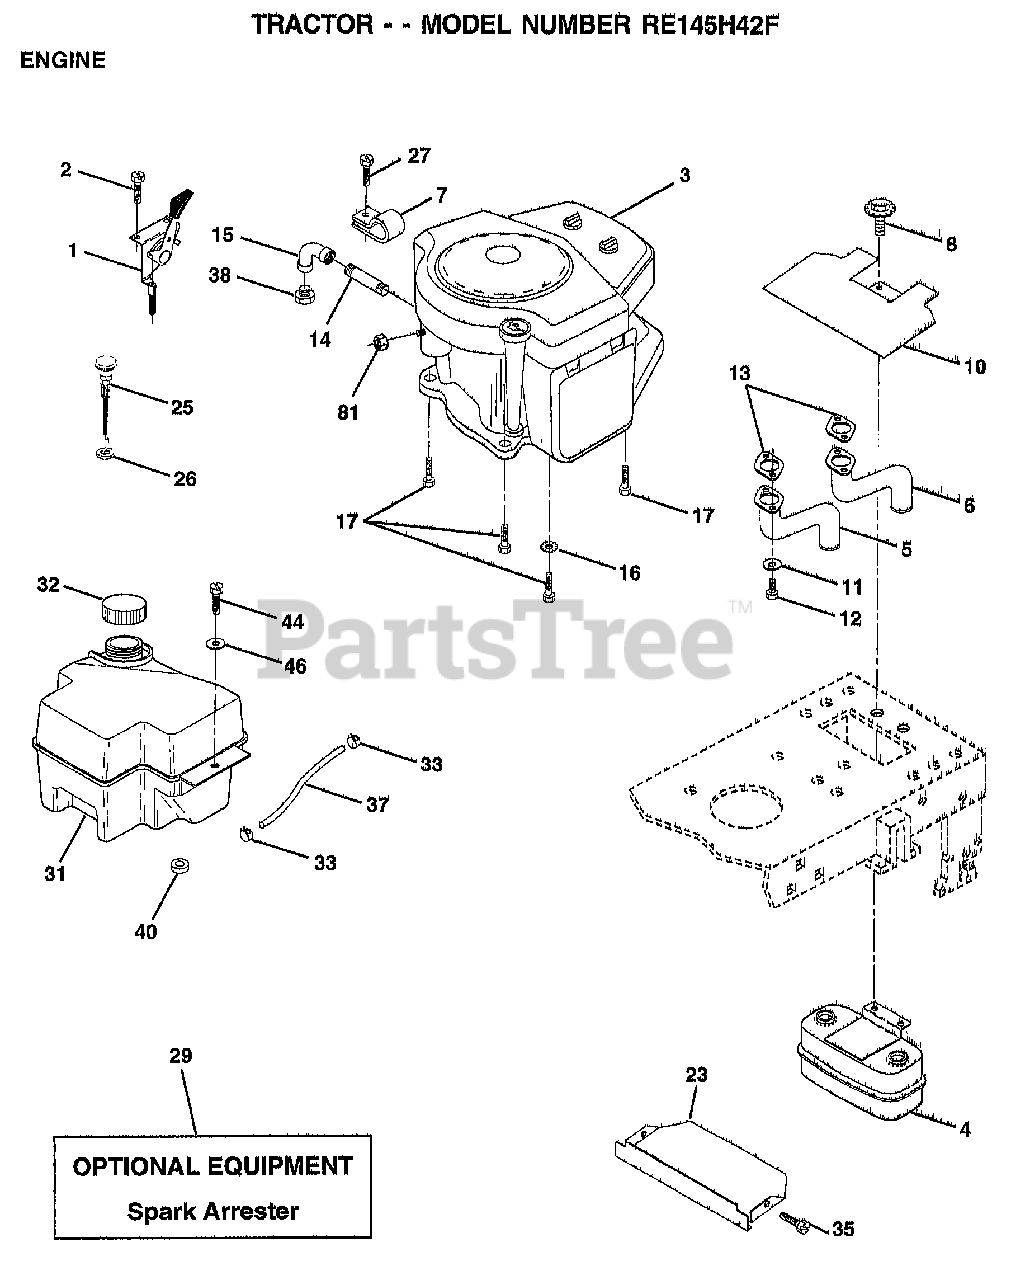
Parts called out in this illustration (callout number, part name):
1	CONTROL THRT 35.5
2	SCREW LT
4	MUFFLER.TW.LOTONE
5	EXHAUST.B&S.18.LH
6	EXHAUST.B&S.18.RH
7	CLAMP.TUBE.DBL.EN
8	BOLT.5/16-18.UNC
10	SHIELD.HEAT.
11	LOCKWASHER
13	GASKET MUFFLER
14	PIPE NIPPLE LT
15	ELBOW
16	LOCKWASHER
17	SCREW LT
23	SHIELD.BRN/DBR.GD
25	CONTROL.CHOKE.37
26	"NUT,KEPS 3/8-24IM"
27	"SCREW-TT,10-32 FL"
31	TANK.FUEL.FRONT.
32	CAP ASM FUEL
33	HOSE CLAMP
35	SCREW
37	LINE FUEL
44	SCREW HEX CRT
46	WASHER
81	NUT
